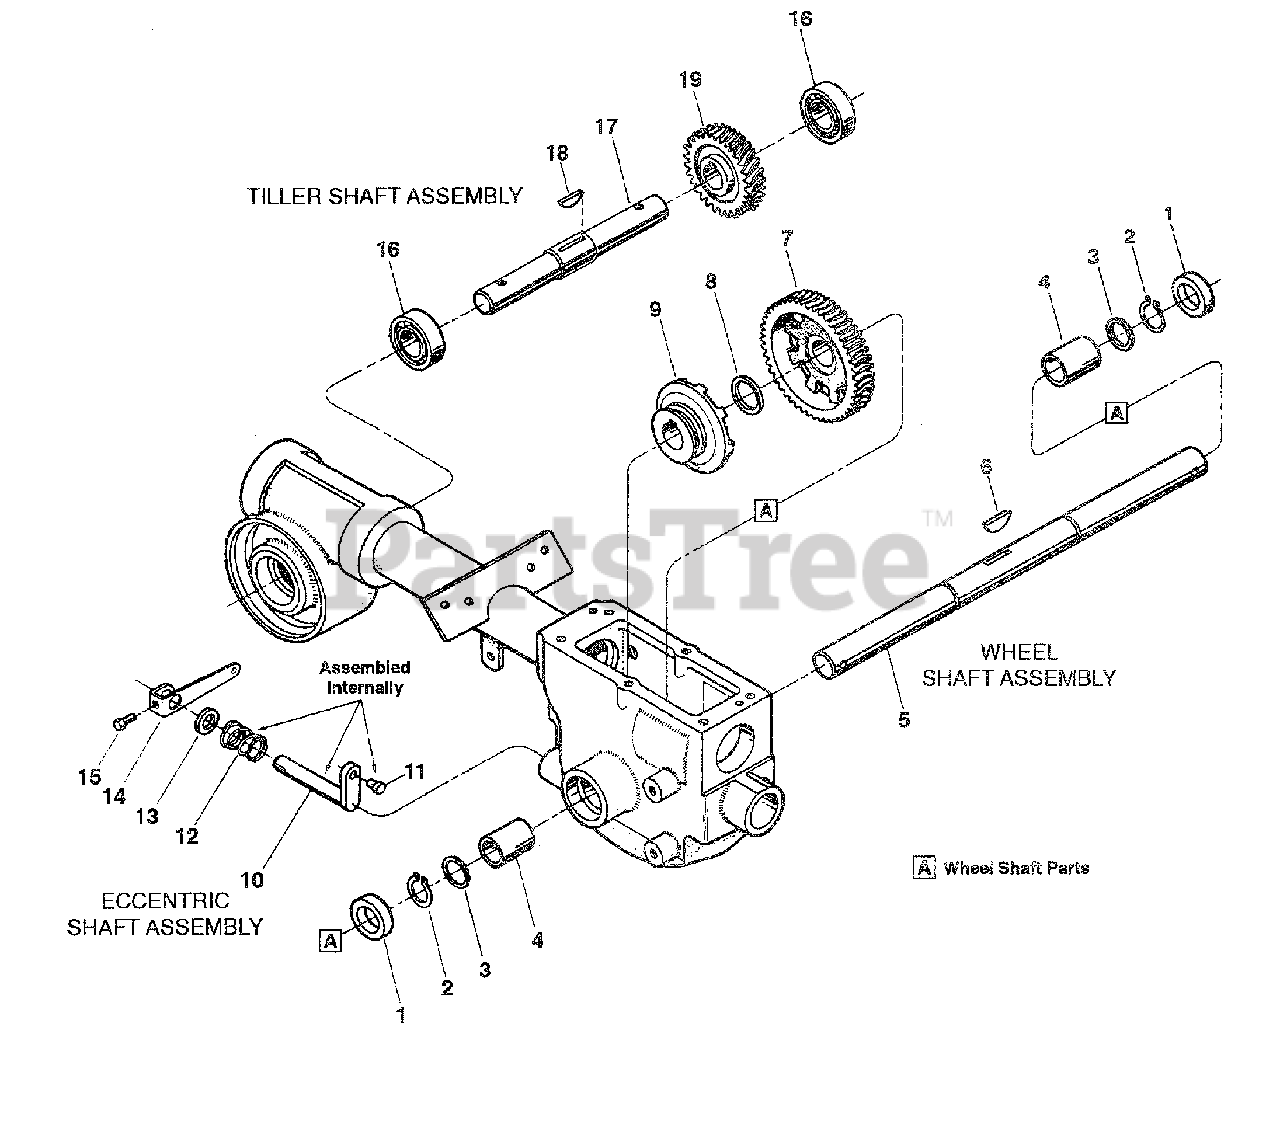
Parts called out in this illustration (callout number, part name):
1	Oil Seal-left and right sides
2	Ring-retaining, heavy-duty, external
3	Shim-1-1/64 I.D., .062 thick
4	Bushing
5	Wheel Shaft (axle)-
6	Key-hi-pro (1/4 x 1-5/16), clutch to wheel shaft
7	Gear-wheel drive (worm gear), cast iron
8	Shim-between key and gear (1.016 I.D. x 1.468 O.D. x .062 thick)
9	Clutch-wheel drive, cast iron
10	Eccentric Shaft wheel clutch shifting
11	Pin-eccentric shaft
12	Spring
13	Oil Seal-eccentric shaft
14	Lever-eccentric shaft
15	Screw-hex hd., 1/4-20 x 1/2
16	Ball Bearing-
17	Tiller Shaft-
18	Key-woodruff, 1/4 x 1-1/4,
19	Worm Gear-bronze, tiller drive
